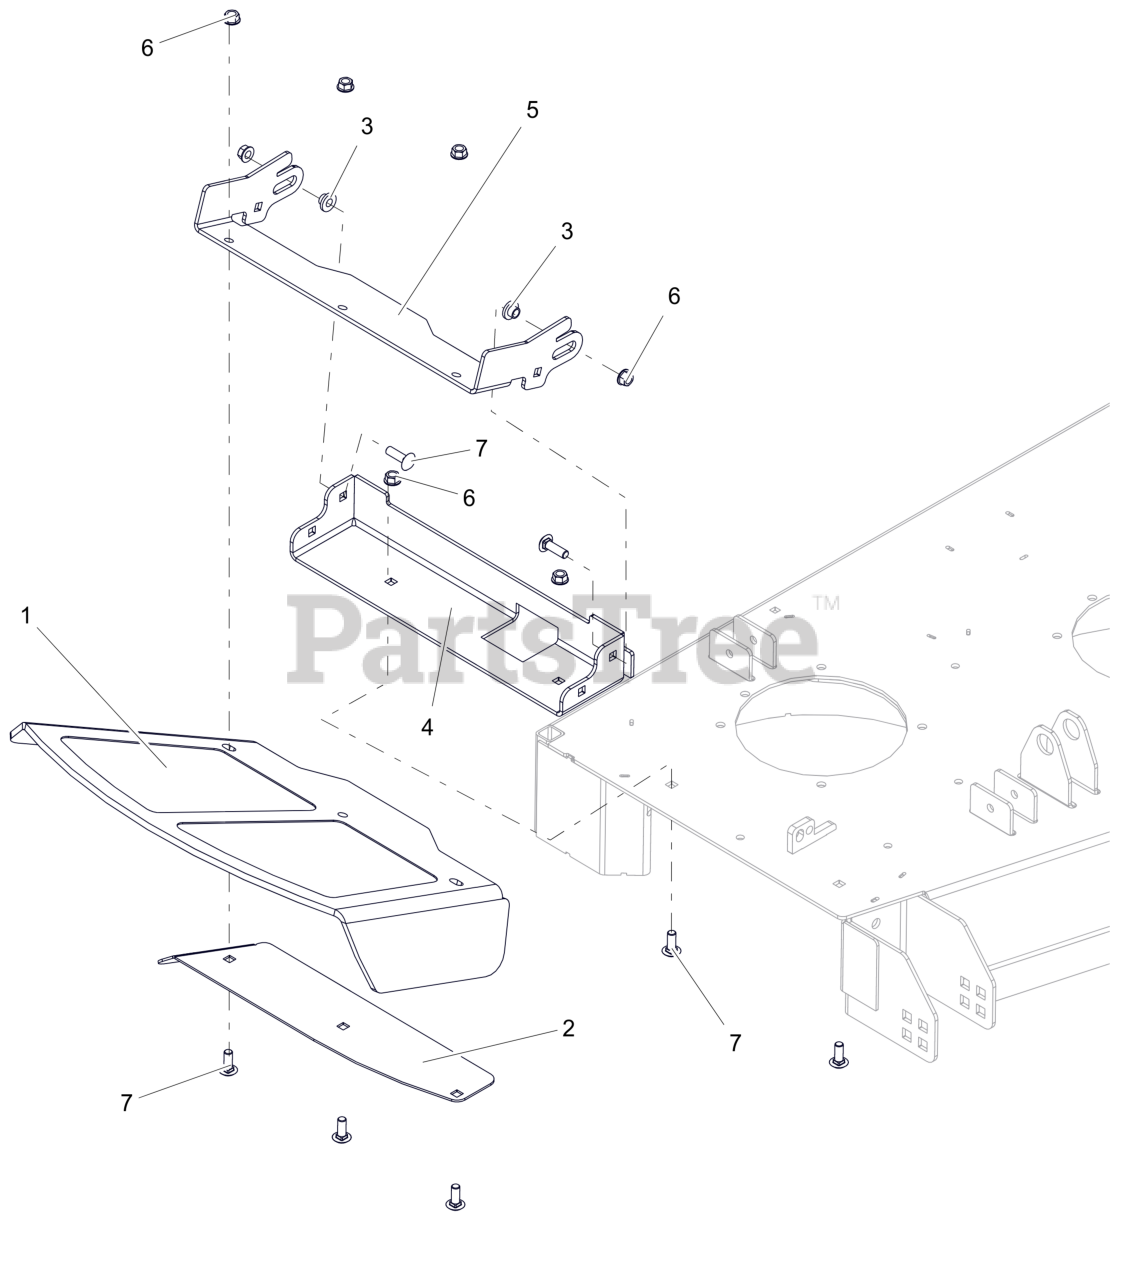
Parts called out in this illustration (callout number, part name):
1	CHUTE, FORMED RUBBER DISCHARGE
2	48-60 DISCH CHUTE CLMP PLT-RED
3	BSHG-FLG .385X.500X.875X.406
4	BASE, 48" DISCHARGE CHUTE MTG BRKT (RED)
5	BRKT- CHUTE MTG
6	NUT-LK-CTR-FLG .375-16 GF ZCC
7	BTL,RHSSN .375-16 X 1
